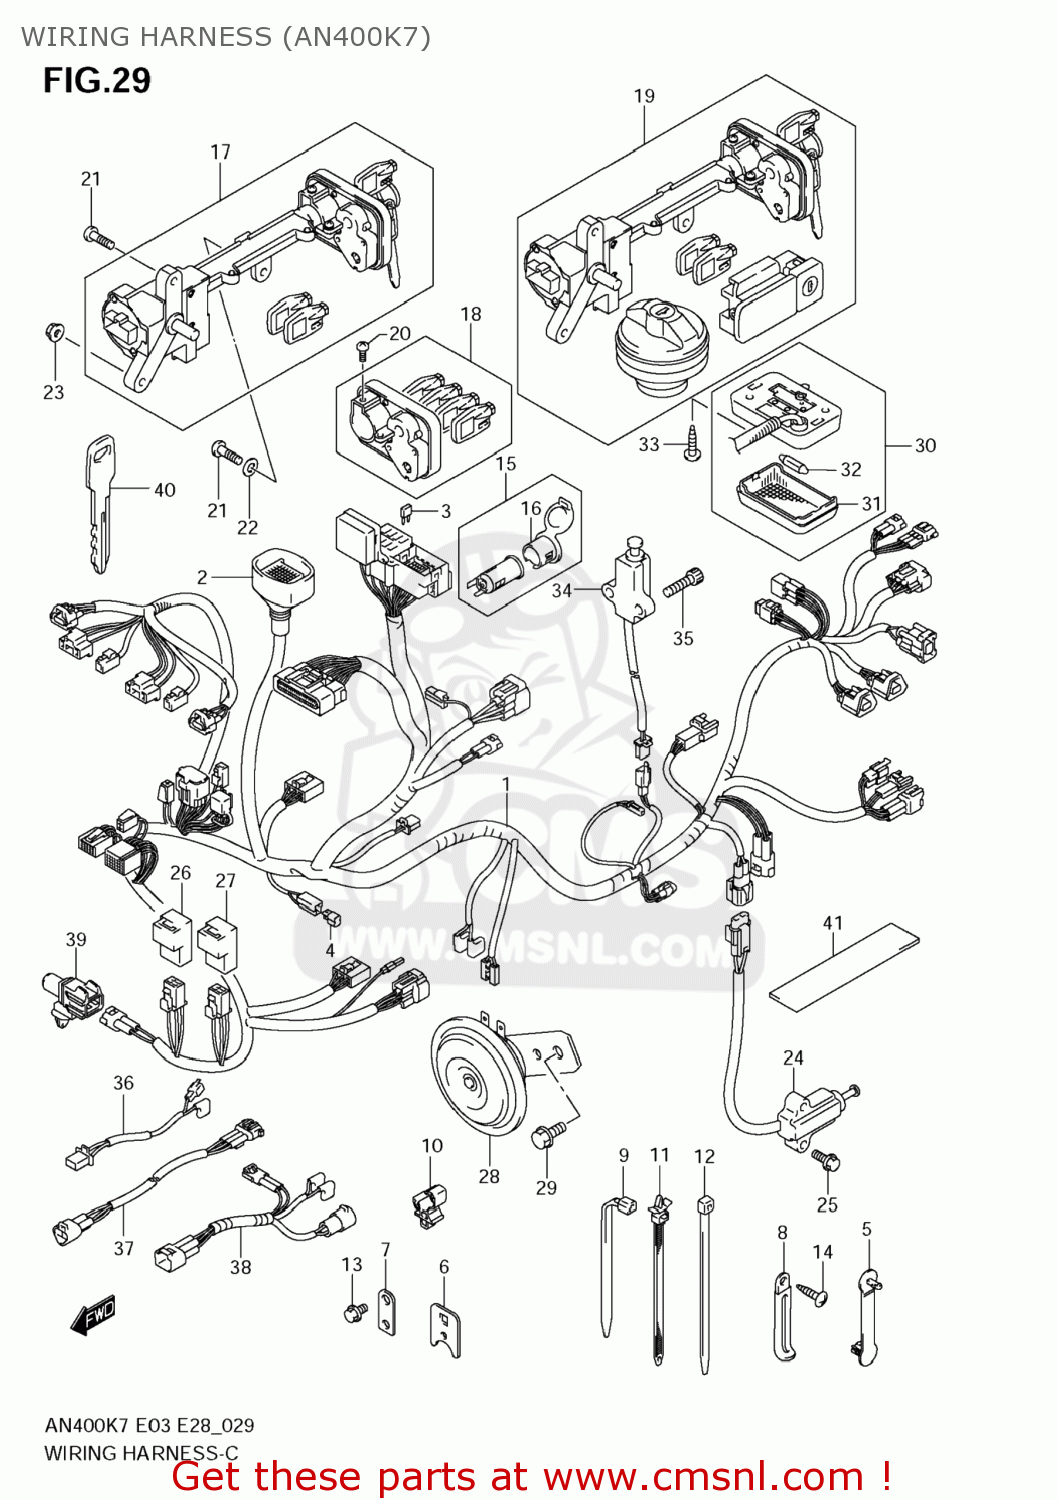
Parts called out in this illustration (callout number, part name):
1	HARNESS,WIRING
2	KABELRUBBER
3	FUSE(10A)
4	RECTIFIER ASSY
5	CLAMP(L:63)
6	BRACKET,LEAD WIRE
7	BRACKET,LEAD WIRE
8	CLAMP(L:45)
9	CLAMP(L:125)
10	CLAMP
11	CLAMP(L:90)
12	CLAMP(L:145)
13	BOLT
14	SCREW
15	SOCKET ASSY
16	COVER
17	LOCK ASSY,STEE
18	SHUTTER,STEERING LOCK
19	LOCK SET
20	TORX BOLT(5X10)
21	SCREW(6X20)
22	WASHER(6.5X18X1.6)
23	NUT
24	SWITCH ASSY,SIDE STAND
25	BOLT
26	RELAY ASSY
27	RELAY ASSY
28	HORN ASSY
29	BOLT
30	LAMP ASSY,TRUNK BOX
31	LENS,ROOM LAMP
32	BULB(12V,5W)
33	SCREW
34	SWITCH ASSY,TRUNK BOX LAMP
35	BOLT
36	WIRE,POWER SOURCE LEAD
37	WIRE,SPEED SENSOR
38	WIRE,IGNITION COIL LEAD
39	SENSOR,AIR TEMP
40	KEY,BLANK
41	PROTECTOR(80X80X2)
